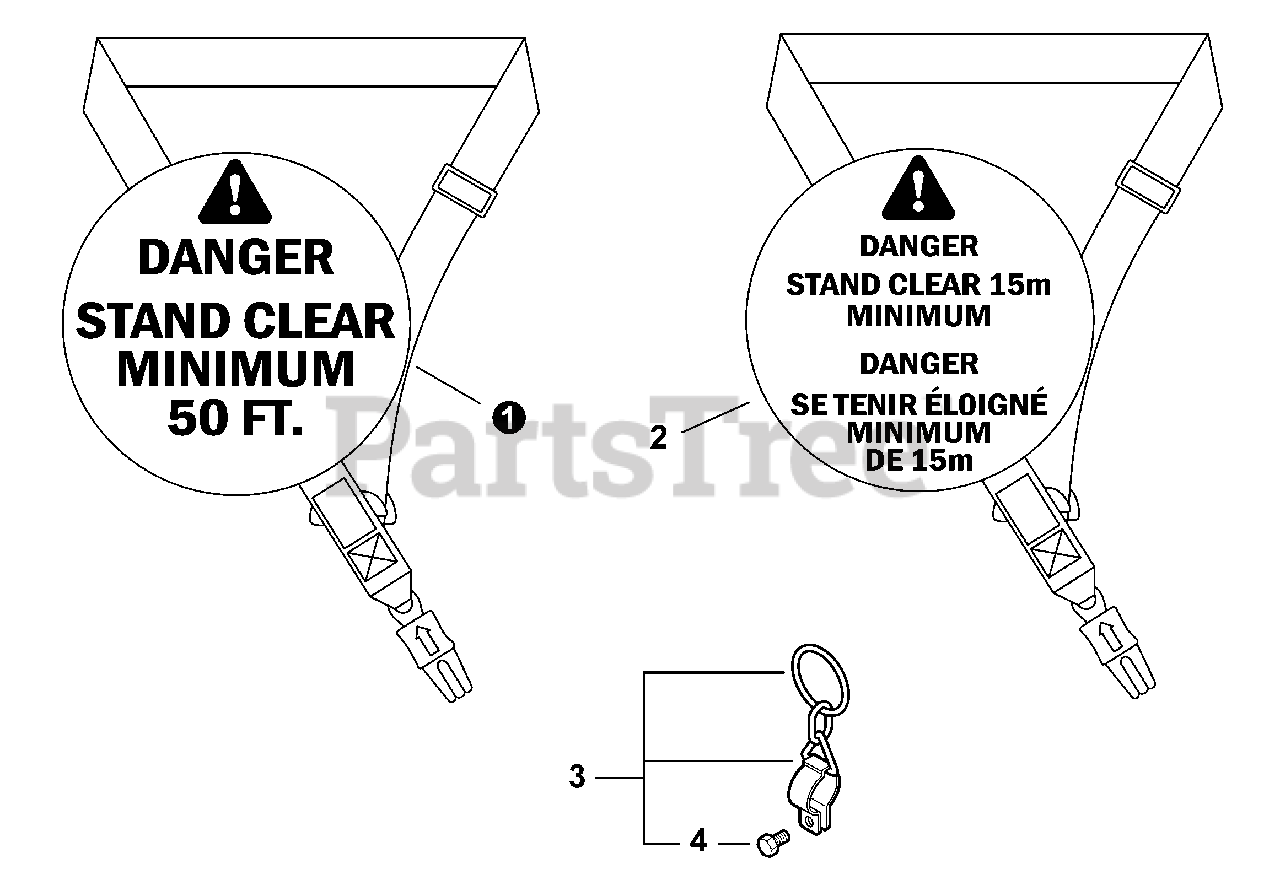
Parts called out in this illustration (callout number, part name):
1	HARNESS, SHOULDER
2	HARNESS, SHOULDER
3	HANGER SET, HARNESS
4	BOLT 5×12
